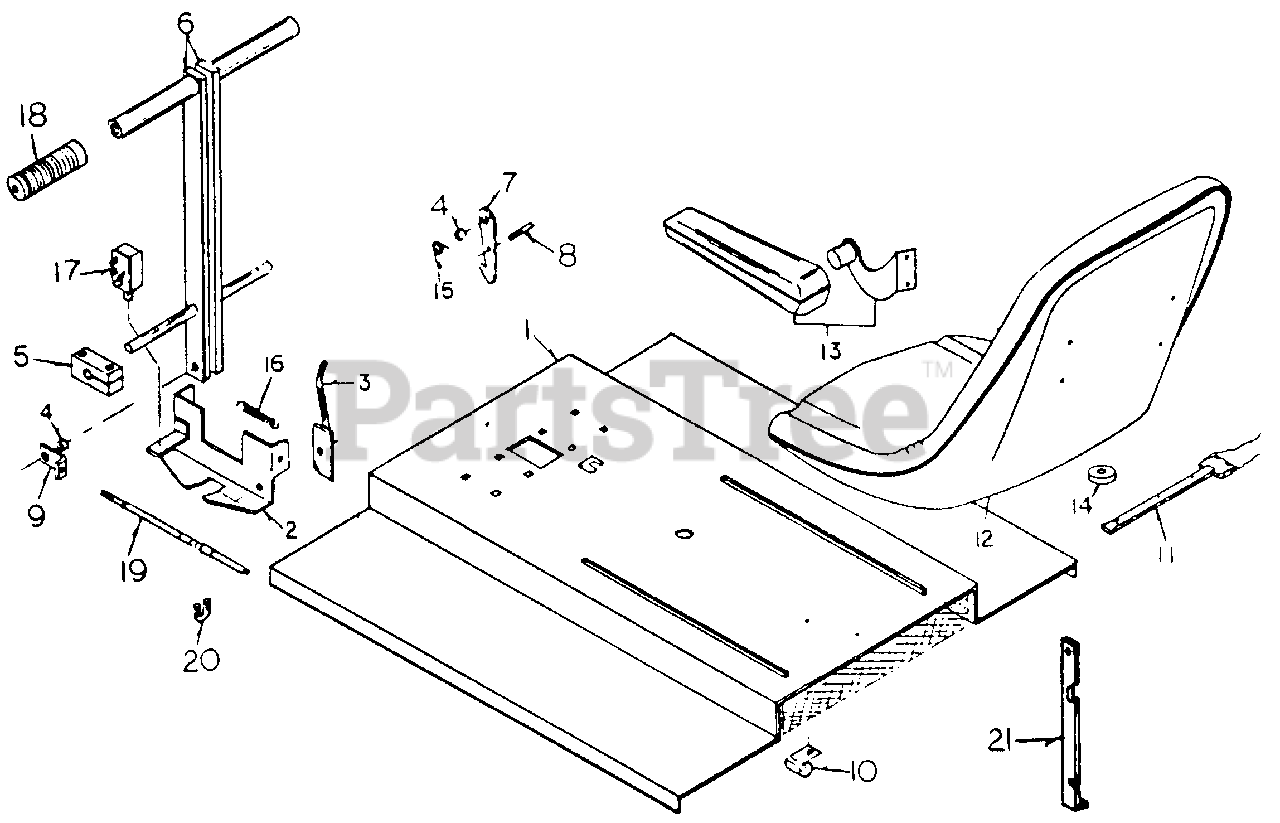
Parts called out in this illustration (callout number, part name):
3	Latch, Lever Lock
4	Bushing
6	Steering Lever
7	Seat Lid Latch
8	Seat Lid Latch Bolt
9	Steering Cable End
10	Seat Lid Harness Retainer
13	Arm Rest Kit
15	Scat Lid Latch Spring
16	Lever Lock Spring
18	Handle Grip
19	Steering Cable
20	Steering Cable Clamp
